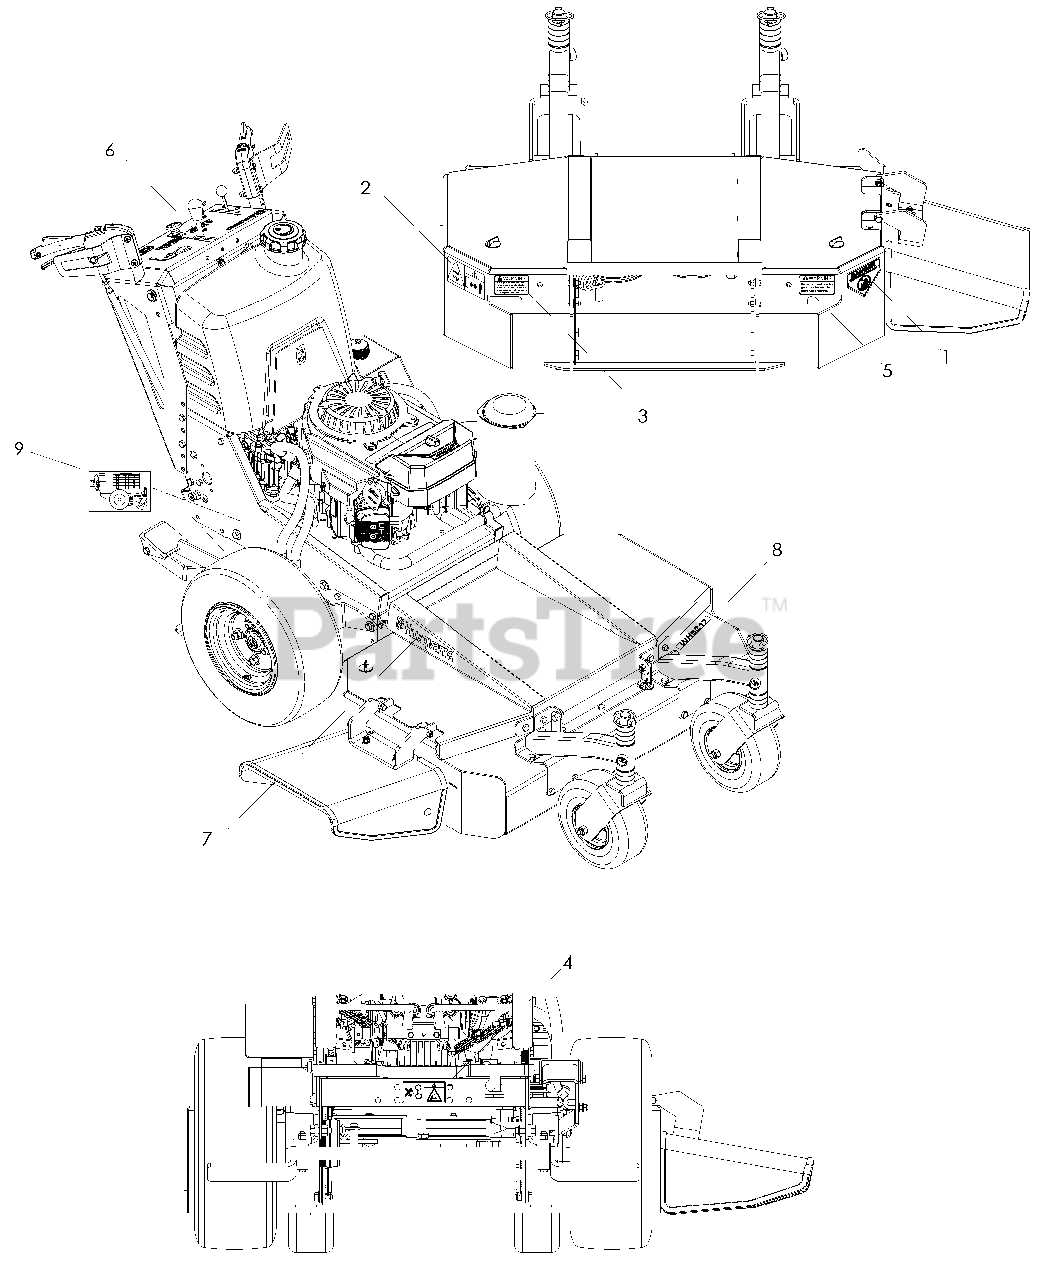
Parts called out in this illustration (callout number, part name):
1	DECAL, WARNING
2	DECAL, SEVERING
3	DECAL, PROP 65
4	DECAL, BELT DRIVES
5	DECAL, WARNING
6	DECAL, INSTRUMENT PNL
7	DECAL, HUSQVARNA
8	DECAL, CROWN
9	DECAL, HEIGHT OF CUT
10	DECAL, WH5217
